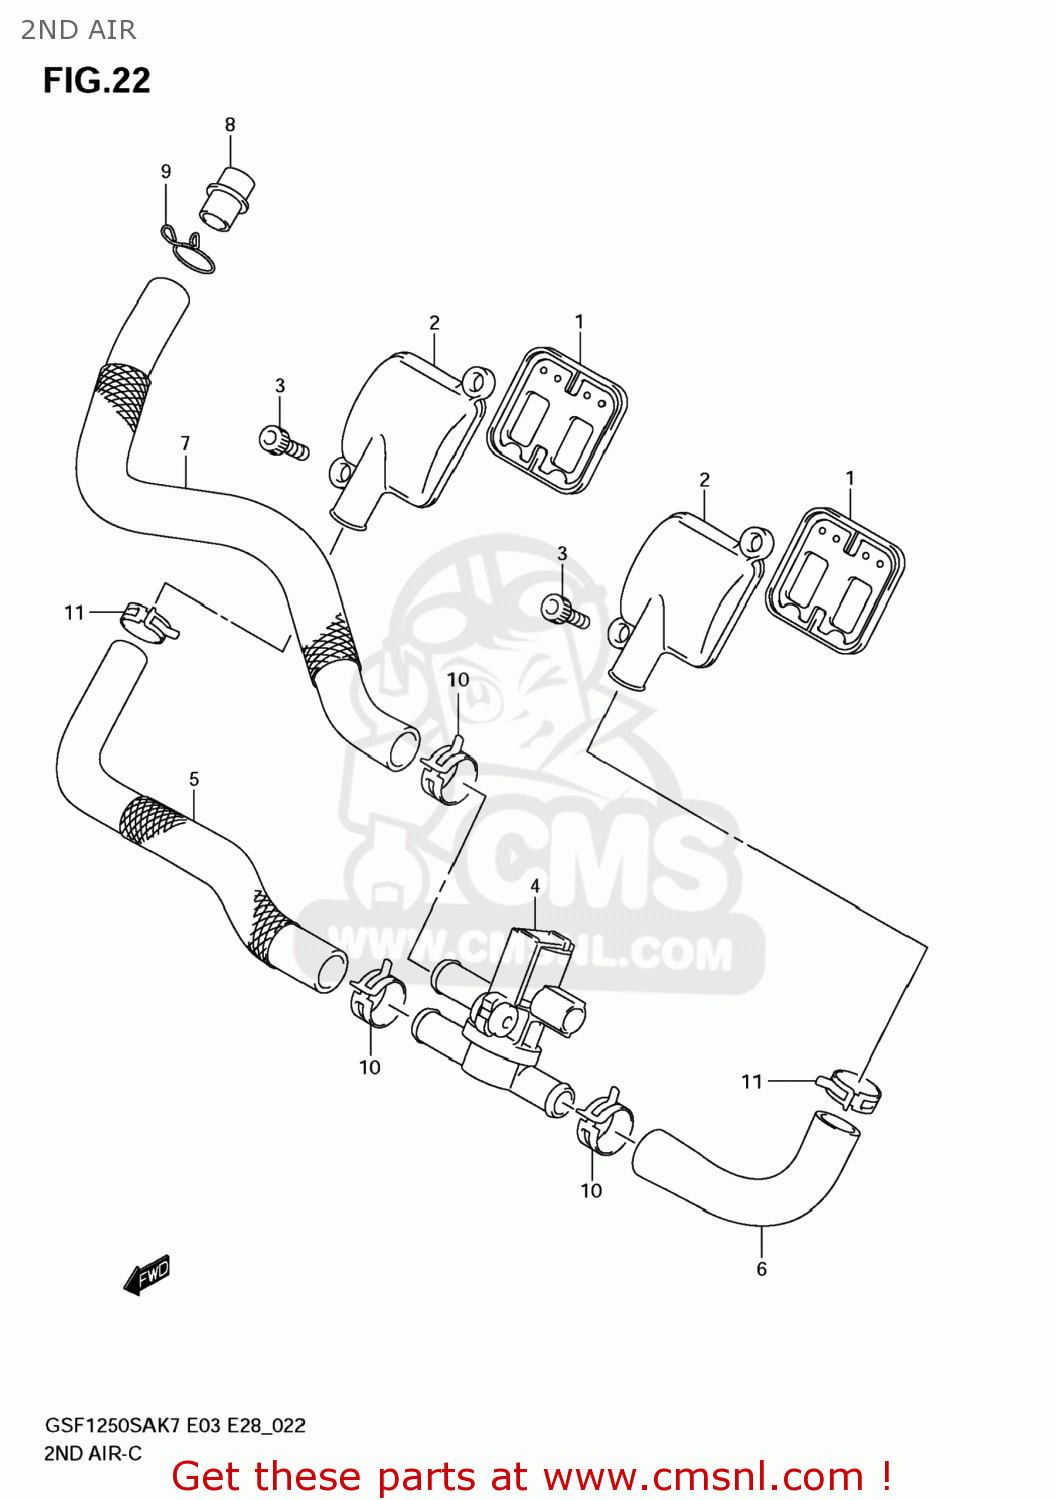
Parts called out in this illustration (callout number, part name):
1	VALVE ASSY,2ND AIR REED
2	COVER,2ND AIR REED VALVE
3	BOLT(6X16)
4	VALVE ASSY,AIR CUT
5	HOSE,2ND AIR VALVE,R
6	HOSE,2ND AIR VALVE,L
7	HOSE,2ND AIR CLEANER
8	JOINT,2ND AIR CLEANER HOSE
9	CLIP
10	CLIP
11	CLIP
